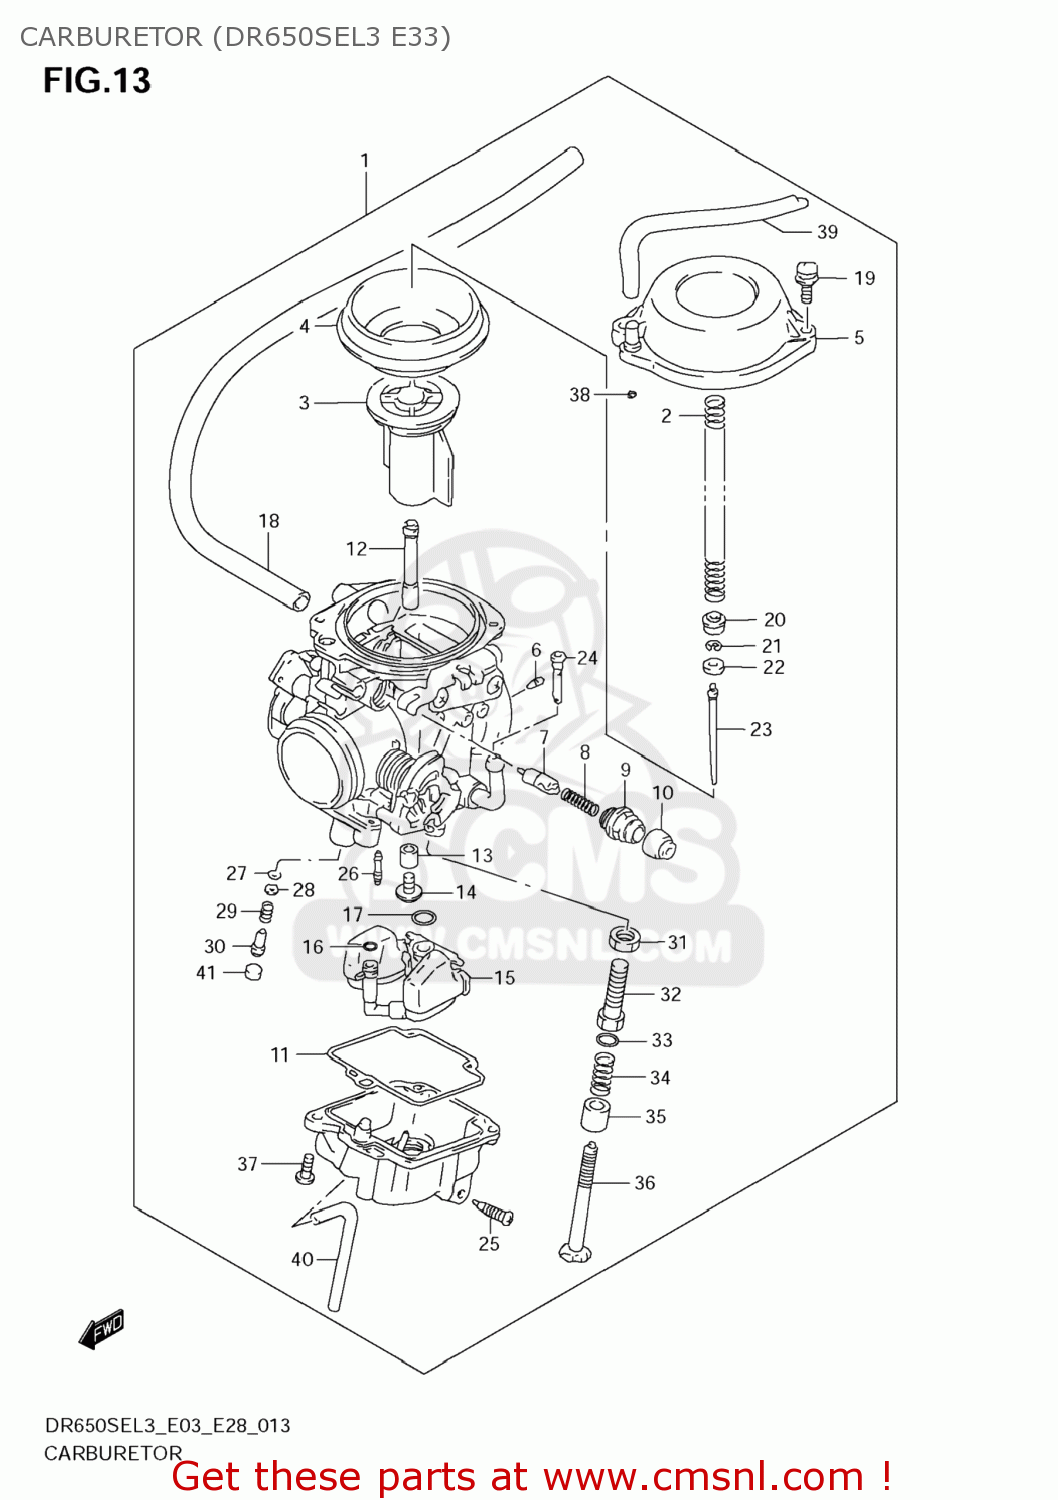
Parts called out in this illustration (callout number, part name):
1	CARBURETOR ASSY
2	SPRING
3	VALVE,PISTON
4	DIAPHRAGM
5	COVER,DIAPHRAGM
6	JET,AIR(1.0)
7	PLUNGER
8	SPRING
9	HOLDER,GUIDE
10	CAP
11	GASKET,FLOAT CHAMBER (NAS)
12	JET,NEEDLE(Y-5M)
13	RING
14	JET,MAIN(140)
15	FLOAT/NEEDLE VALVE ASSY
16	O RING
17	O RING,NEEDLE VALVE SEAT
18	HOSE(6.5X10.5X275)
19	SCREW
20	RING
21	CLIP,NEEDLE
22	RING
23	NEEDLE,JET(6F23)
24	FILTER
25	SCREW,DRAIN
26	JET,PILOT(42.5)
27	O RING,PILOT AIR SCREW
28	WASHER
29	SPRING
30	SCREW,PILOT
31	NUT
32	ADJUSTER
33	WASHER,STARTER SHAFT
34	SPRING
35	RING
36	ADJUSTER
37	SCREW(5X14)
38	O RING
39	HOSE(4.5X8.5X600)
40	HOSE(3X5X450)
41	PLUG
